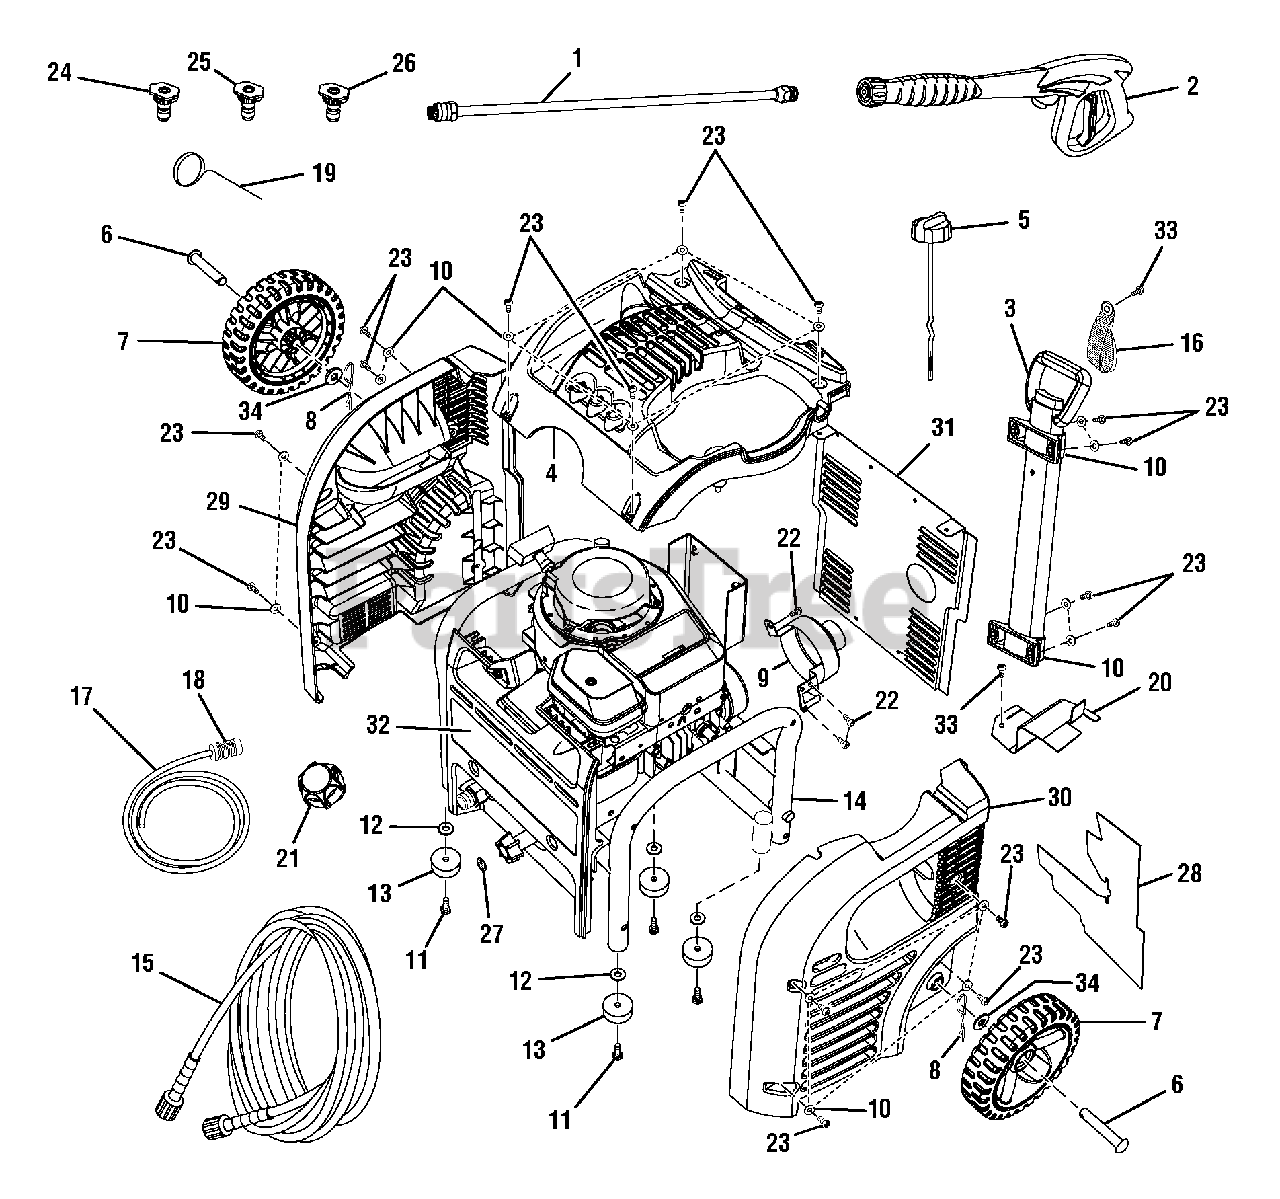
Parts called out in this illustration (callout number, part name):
1	Spray Wand Extension
2	Spray Wand
3	Handle Assembly
4	Panel, Top
5	Oil cap / Dipstick
8	Hitch Pin
9	Muffler Cover
10	Lock Washer (1/4 in)
11	Bolt (1/4-20 x 3/4 in Hex Hd)
12	Washer, 1/4 in
13	Rubber Foot
14	Frame Assembly
15	High Pressure Hose
16	Hook and Loop Strap
17	Injection Hose
18	Injection Hose Filter
19	Nozzle Cleaning Tool
20	Heat Isolator, upper
22	Screw (M5 x 8 mm)
23	Screw (1/4-20 x 18 mm)
24	Nozzle, 0° (Red)
25	Nozzle, 25° (Green)
26	Nozzle, Detergent (Black)
27	Filter Screen
28	Heat Isolator, lower
29	Panel, left side
30	Panel, right side
31	Panel, back
32	Panel, front
33	Screw (12-14)
34	Rubber Washer
35	Bolt (M8 x 50 mm Hex Hd)
36	Nut (M8)
